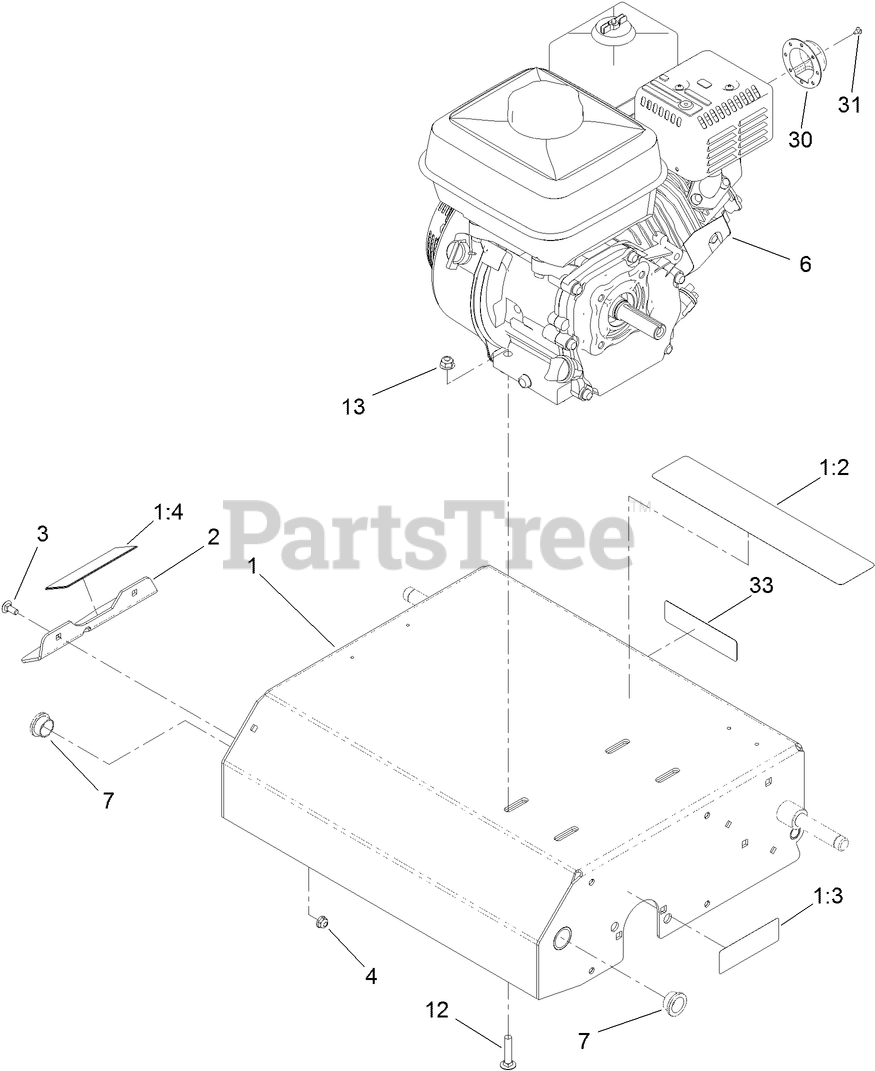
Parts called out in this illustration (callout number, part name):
1	FRAME ASM
1:2	DECAL-WARNING
1:3	DECAL-WARNING, SHIELDS
1:4	DECAL-DANGER
2	GUARD-HAND
3	SCREW-CARR
4	NUT-HF
7	BUSHING
12	BOLT-CARR
13	NUT-HF, NI
30	DEFLECTOR
31	SCREW-PPHTF
33	DECAL-ARRESTER, SPARK
